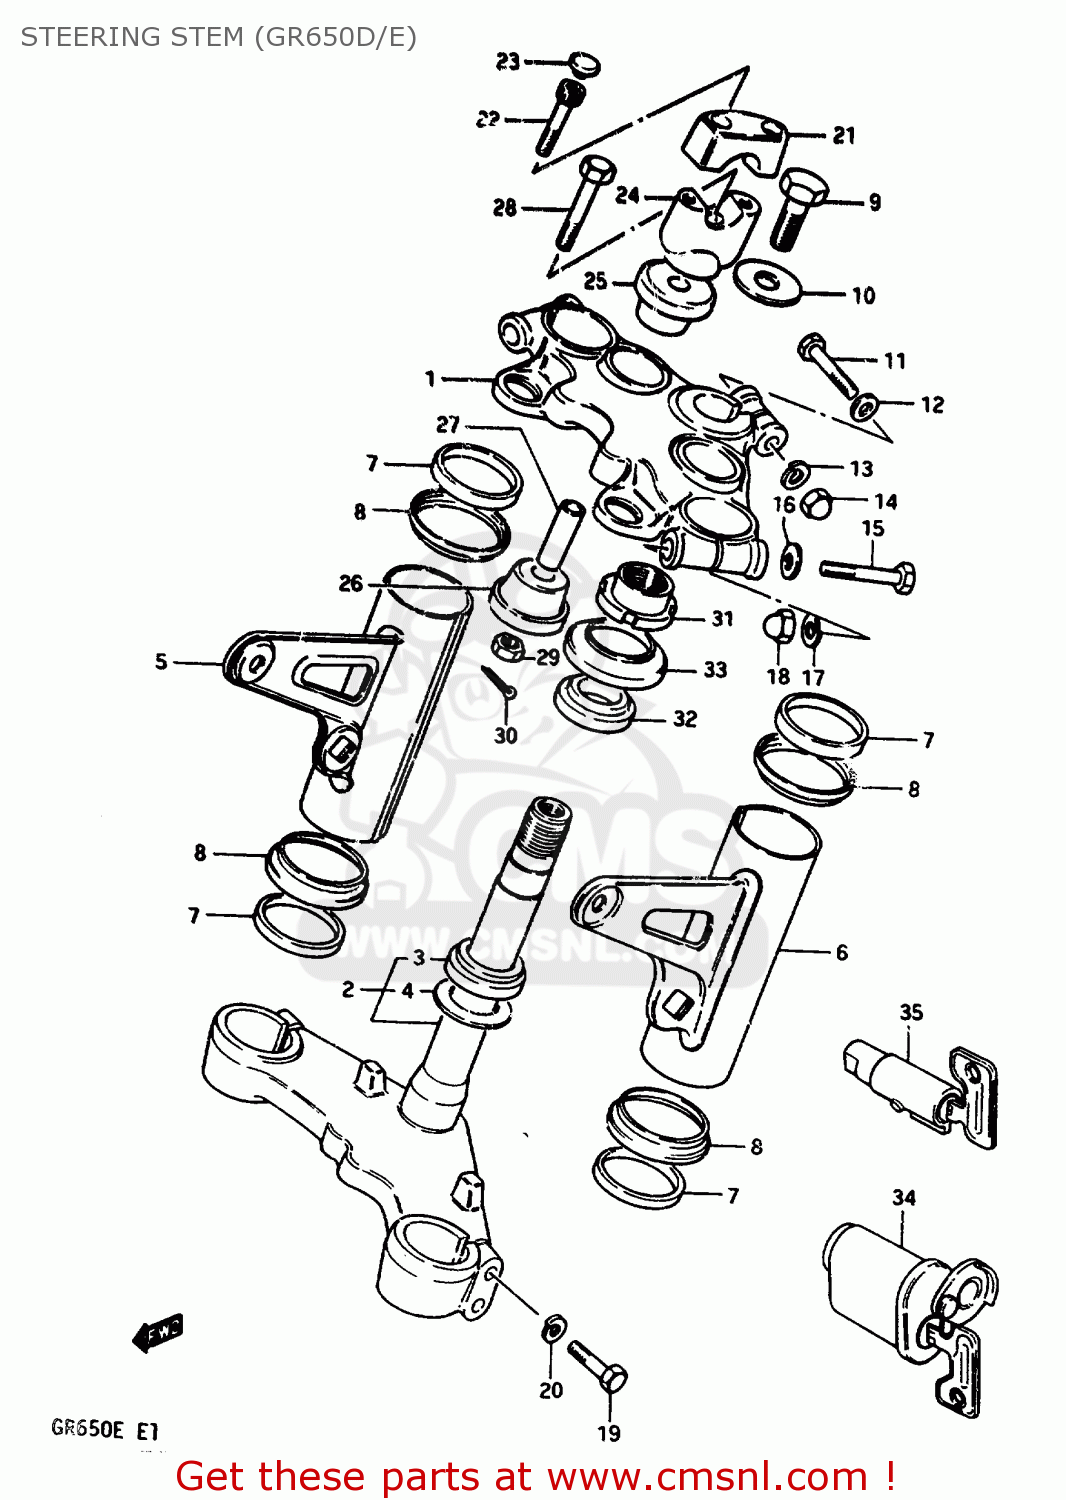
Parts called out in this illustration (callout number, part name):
1	HEAD,STEERING STEM
2	STEM,STEERING
3	BEARING
4	WASHER,THRUST
5	BRACKET COMP,HEADLAMP
6	BRACKET,HEADLAMP,LEFT
7	CUSHION,HEADLAMP BRACKET
8	CAP,HEADLAMP BRACKET
9	BOLT,STEERING STEM HEAD
10	WASHER
11	BOLT 8X50
12	WASHER
13	LOCK WASHER
14	NUT,M8X1.25X12
15	BOLT 10X55
16	WASHER 10MM
17	LOCK WASHER
18	NUT
19	BOLT 8X40
20	LOCK WASHER
21	CLAMP,HANDLE BAR,UPPER
22	BOLT
23	CAP(OD:14.5)
24	CLAMP,HANDLE BAR,LOWER
25	CUSHION,LWR
26	CUSHION,LWR
27	SPACER(10.2X14X46)
28	BOLT(10X78)
29	NUT
30	COTTER PIN
31	NUT,STEERING STEM
32	TAPER,ROLLER BEARING
33	DUST SEAL,STEERING UPR
34	LOCK ASSY, STEERING (NEIMAN TYPE EXECUTE
35	LOCK ASSEMBLY,STEERING (NEI
